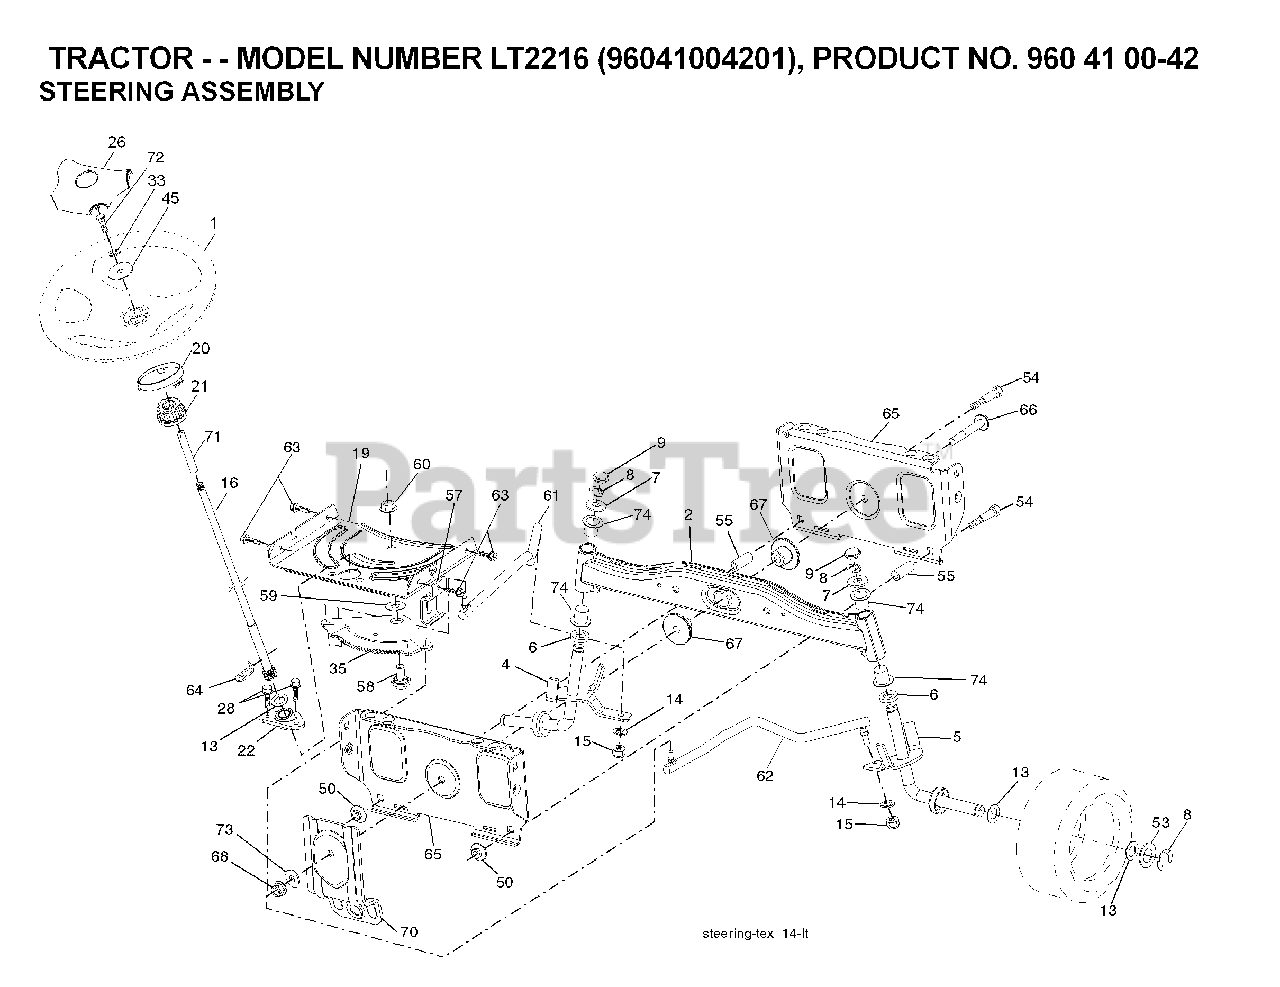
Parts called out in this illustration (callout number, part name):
2	AXLE.HALF.ASM.WELDED
4	SPINDLE.WELDED.LH.15"TEX
5	SPINDLE.WELDED.RH.15"T
8	RING CLIP
9	CAP.SPINDLE
14	WASHER, LOCK 3/8
15	NUT CROWNLOCK 3/8-24
16	SHAFT STEERING
19	PLATE.STEER.DDL.NLT/NG
20	BOOT STEERING BLACK
21	ADAPTER, WHEEL STNG..
22	BUSHING.ASM.STEERING.A
26	INSERT.CAP.STRG.WH.BLACK
28	SCREW, 3/8-16X3/4
33	LOCKWASHER
35	GEAR.SECTOR.PLATE.DDL.
45	WASHER.11/32
50	NUT LOCK FLG 3/8-16 UNC
53	WASHER.HARDENED
55	SPACER.BRACE.AXLE
57	BRACKET.UPSTOP.TEX
58	BOLT.SHOULDER.SECTOR.P
59	WASHER.THURST.SECTOR.S
60	NUT FLANGE LOCK 5/8-11
61	DRAGLINK.LH.BALLSTUD.D
62	DRAGLINK.RH.BALLSTUD.D
63	SCREW
64	RETAINER.CLIP.SPRING.S
65	BRACE.AXLE.FRONT.NLT/N
66	BOLT HEX FGHD 7/16-14 X 3 SERR
67	BUSHING.PM.FRONT AXLE
68	NUT.LOCK.FLANGE.7/16
70	BRKT.DECK.SUSPENSION.F
71	SHAFT EXTENSION STEERING
72	BOLT YT
73	WASHER.1.5X.505X.118
74	BRNG T
